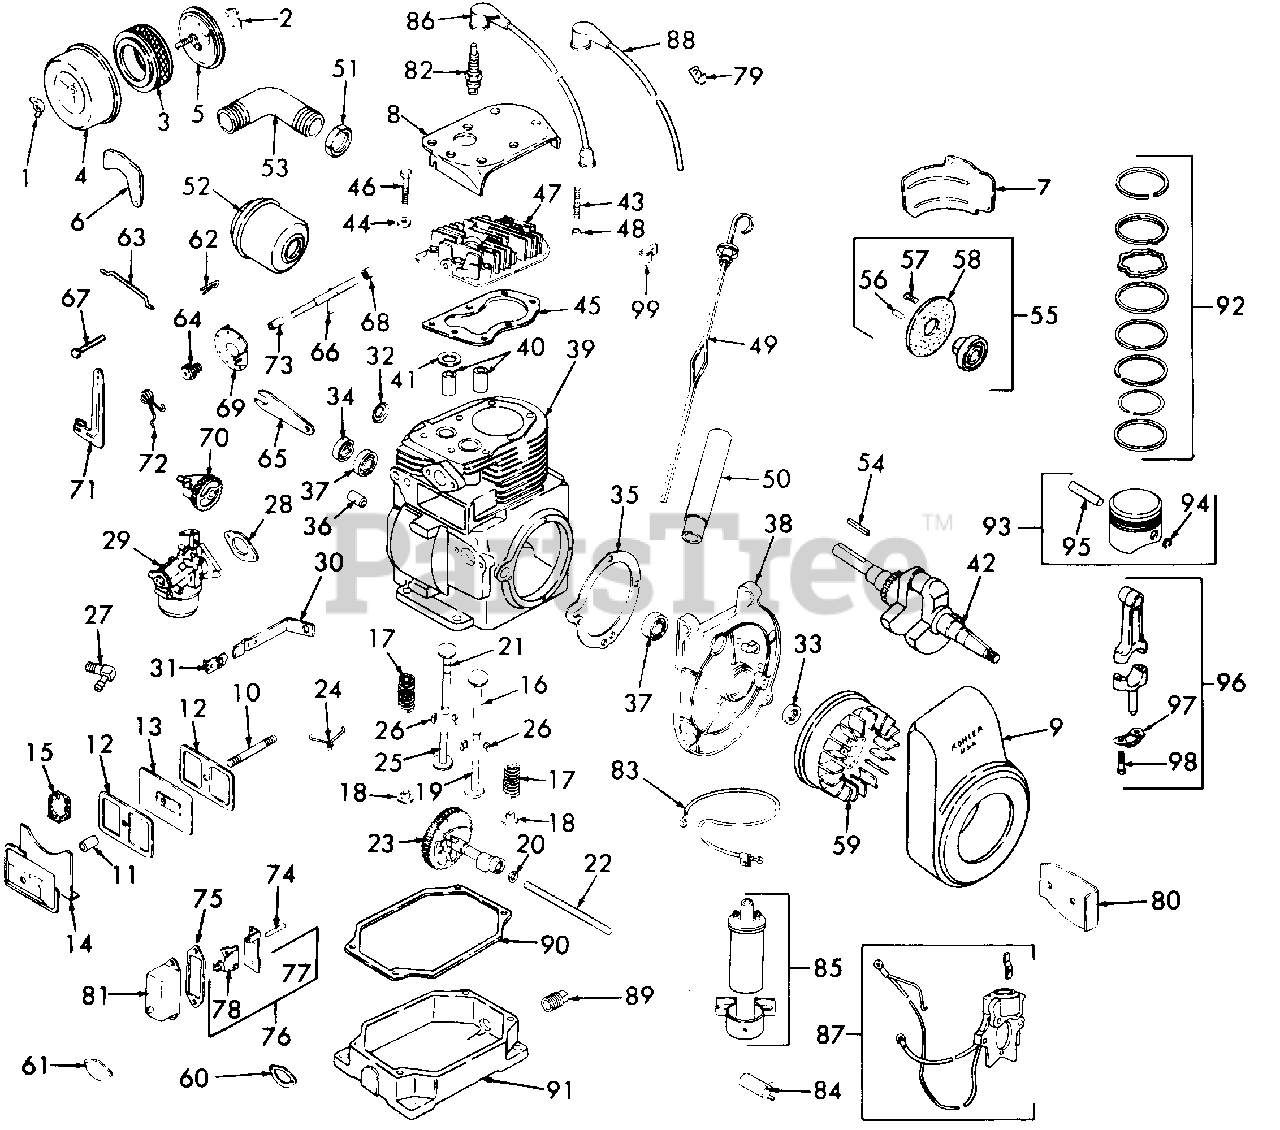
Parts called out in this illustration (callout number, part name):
1	Nut, 1/4-20 Wing
3	Element, Air Cleaner
4	Cover, Air Cleaner
5	Base, Air Cleaner
6	Baffle, Side Air
7	Baffle, Cylinder
8	Baffle, Head
9	Housing, Blower
10	Stud, Valve Cover
11	Seal, Breather
12	Gasket, Valve Cover
13	Breather Assy
14	Cover Assy, Valve
15	Filter
16	Valve, Intake
17	Spring, Valve
18	Retainer, Spring
19	Tappet, Intake Valve
20	Spacer, Camshaft, .005
21	Valve, Exhaust
22	Pin, Camshaft
23	Camshaft Assy
24	Spring, Actuating
25	Tappet, Exhaust Valve
26	Keeper, Spring
28	Gasket, Carburetor
29	Carburetor Assy
30	Bracket, Choke
32	Plug, Expansion
33	Seal, Front Oil
34	Seal, Rear Oil
36	Shaft, Governor
37	Bearing, Ball
38	Plate, Bearing
39	Mini Block Assy
40	Guide, Valve
41	Insert, Exhaust Valve
42	Crankshaft
43	Stud
45	Gasket, Head
46	Screw, 5/16-18 x 1-1/2 Hex Cap
47	Head, Cylinder
49	Dipstick Assy
50	Tube, Oil Fill
51	Nut, Lock
52	Muffler
53	Elbow, Exhaust
54	Key
55	Cup Assy, Flywheel Drive
56	Pin, 1/4 x 3/4
58	Screen
59	Flywheel
60	Gasket, Fuel Pump Pad
61	Cover, Fuel Pump Pad
62	Pin
63	Linkage, Governor
64	Bushing, Governor
65	Bracket, Speed Control
66	Shaft, Governor
67	Pin, Governor Stop
68	Bearing, Needle
69	Disc, Regulating
70	Gear, Governor
71	Lever, Governor
72	Spring, Governor
73	Spacer
74	Rod, Breaker
75	Gasket, Cover
76	Breaker Assy
77	Bracket, Breaker Point
80	Bracket, Coil
81	Cover, Breaker
82	Plug, Spark
83	Lead, Breaker
84	Condenser
85	Coil, Ignition
86	Cable, High Tension
87	Stator Assy
88	Lead, Hi-Tension
89	Plug, 3/8 Pipe
92	Ring Set, Piston, Std
93	Piston Assy, Std
94	Retainer, Pin
95	Pin, Piston, Std
96	Rod Assy, Connecting, Std
97	Lock, Connecting Rod
98	Screw, Connecting Rod
99	Clip, Choke Cable
